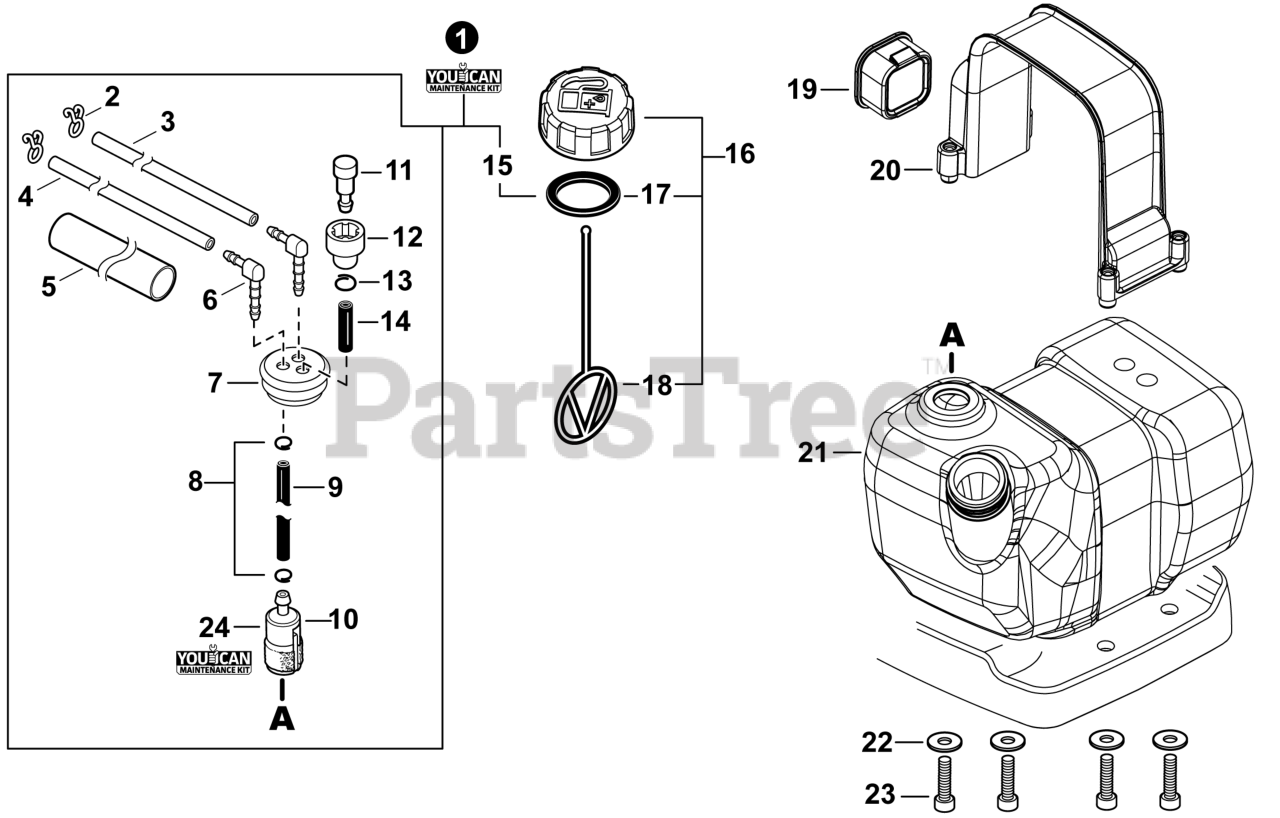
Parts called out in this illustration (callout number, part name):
1	FUEL SYSTEM KIT - YOUCAN?
2	CLIP, SPRING 5.2
3	PIPE, FUEL 3x6x170 YELLOW
4	PIPE, FUEL 3.5x6x160 CLEAR
5	TUBE, INSULATOR 16x18x90
6	CONNECTOR, PIPE
7	GROMMET, FUEL
9	PIPE, FUEL 3x5x210 BLACK
10	FILTER, FUEL
11	VENT ASSY
12	HOLDER, VENT
13	CLIP 6.5 MM
14	PIPE, FUEL 3x6x30 BLACK
15	GASKET, FUEL CAP
16	CAP ASSY, FUEL
17	GASKET, FUEL CAP
18	CONNECTOR, CAP L= 123
19	CUSHION
20	BAND, FUEL TANK
21	TANK, FUEL
22	WASHER 5.5x16x0.8
23	BOLT 5x20
24	TUNE-UP KIT - YOUCAN?
